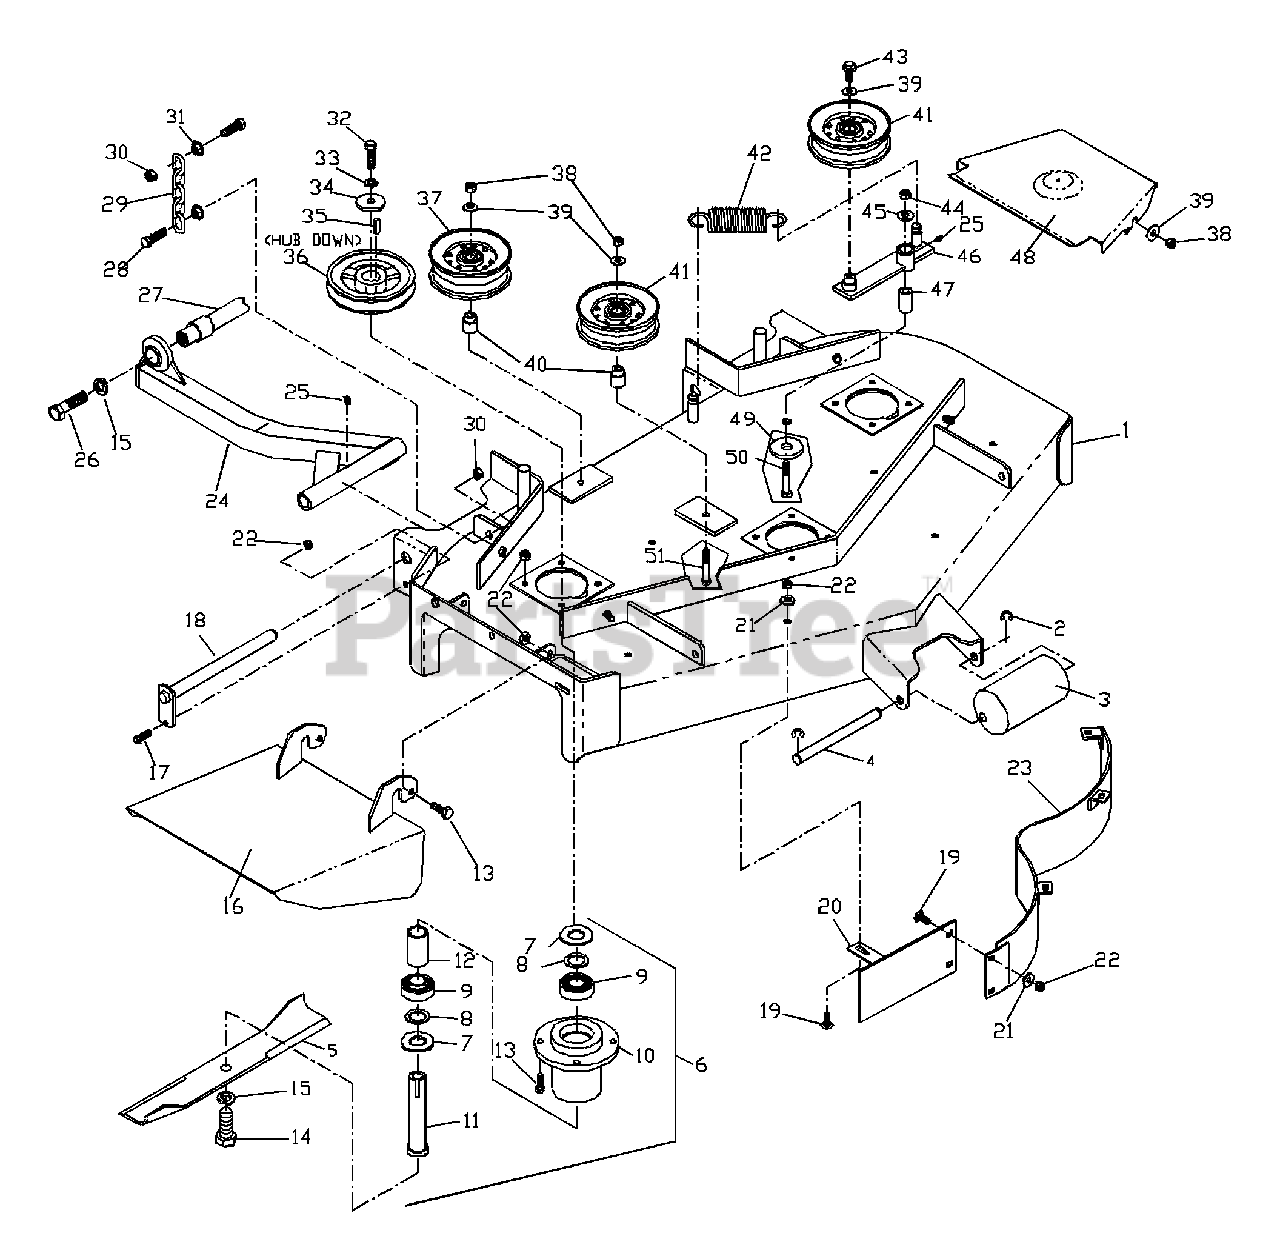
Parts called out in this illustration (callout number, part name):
1	DECK W/DECALS
2	1/2" E-RING
3	ROLLER, LONG
4	AXLE, ROLLER
5	BLADE 14 7/8"
6	CUTTER HOUSING, COMPLETE
7	MACHINERY BUSHING 10GA.
8	MACHINERY BUSHING 18GA.
9	BEARING
13	HCS 5/16C X 1
14	HCS 5/8F X 1 1/4
15	LOCKWASHER
16	DISCHARGE CHUTE
17	HCS 5/16C X 3/4
19	CARRIAGE BOLT 5/16 X 5/8
20	CENTER BAFFLE
21	WASHER 5/16 STD.
22	NUT 5/16 CTR. LOCK
23	MAIN BAFFLE
24	STRUT - RIGHT
24	STRUT - LEFT
25	1/4-28 ZERK
26	HCS 5/16C X 2
27	STRUT MT. WLD.
28	HCS 7/16C X 1 1/2
30	7/16C CTR. LOCK
31	7/16C WHIZ NUT
32	HCS 7/16F X 1 1/2
33	7/16 LOCKWASHER
35	KEY 1/4 SQ. X 1 1/8
37	IDLER PULLEY 1.62
38	NUT 3/8C CTR. LOCK
39	WASHER 3/8 STD.
40	IDLER BUSHING
41	IDLER PULLEY 1.31
43	HCS 3/8C X 1
44	NUT 1/2C NYLOC
45	WASHER 1/2 STD.
47	PIVOT BUSHING
48	BELT SHIELD
49	SUPPORT WASHER
50	HCS 1/2C X 3 1/4
51	HCS 3/8C X 2 1/2
53	DECAL, NO STEP
54	DECAL, CPSC
55	DECAL, DANGER
